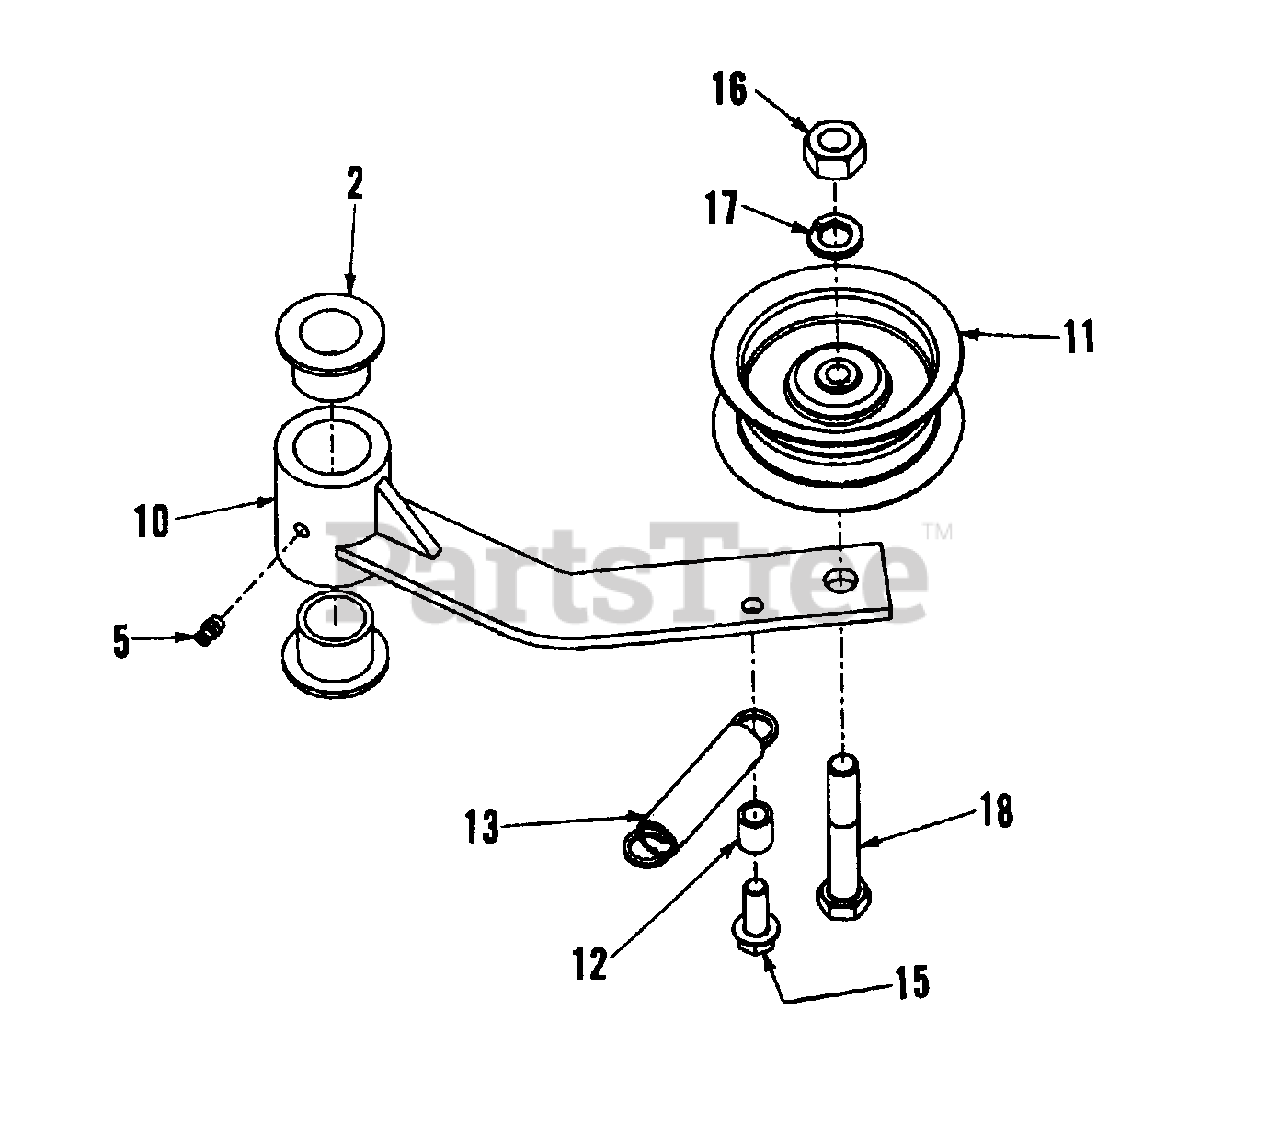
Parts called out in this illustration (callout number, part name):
2	BUSHING, Caster
5	FITTING, Lube 1/4-28 Straight
10	WELDMENT, Idler Arm
11	PULLEY, Flat Idler- 3-1/4" O.D.
13	SPRING, Extension
15	SCREW, 3/8-16 x 1", Hex Washer Self-Tap
16	NUT, 1/2-13 Hex, Grade 5 or B
17	WASHER, 1/2" Split Lock
18	SCREW, 1/2-13 x 3" Hex Head Cap
